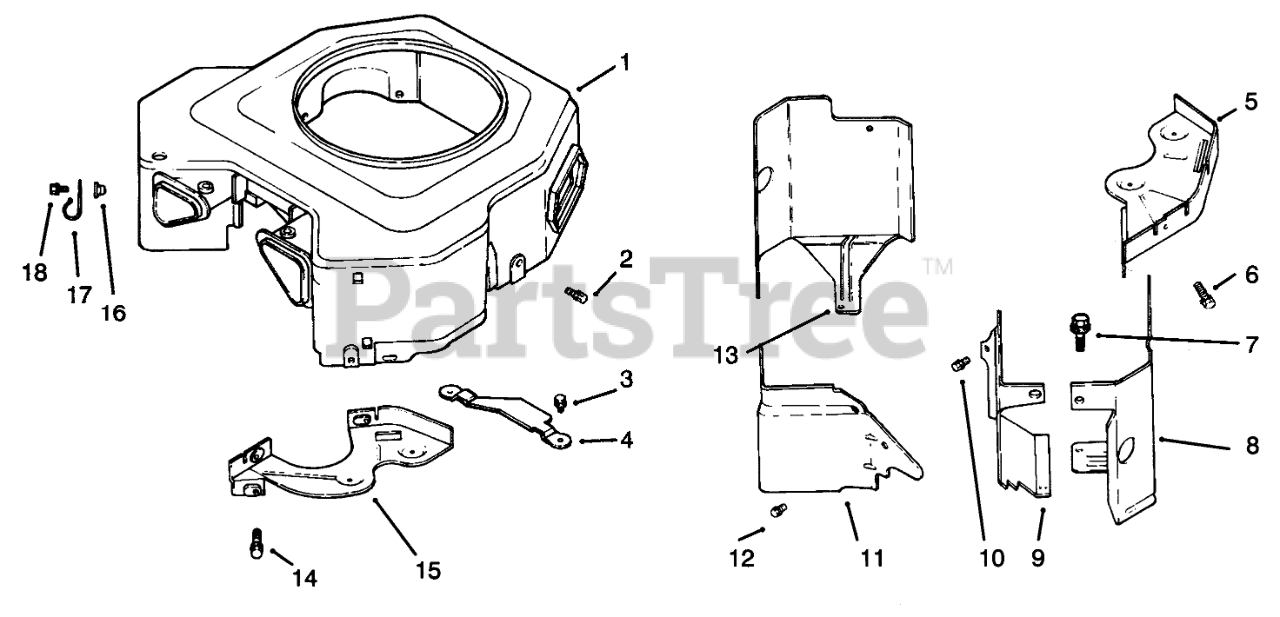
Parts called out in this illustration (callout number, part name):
1	Housing-Blower ASM (Only On: 72103)
2	Screw M5x0.8x16 (Only On: 72103)
3	Screw M6x1.0x16 (Only On: 72103)
4	Guard-Flywheel (Only On: 72103)
5	Plate-Backing #2 Side (Only On: 72103)
6	Screw M5x0.8x20 (Only On: 72103)
7	Screw M5x0.8x14 (Only On: 72103)
8	Baffle-Cylinder #2 Side (Only On: 72103)
9	Baffle-Valley #1 Side (Only On: 72103)
10	Screw M5x0.8x10 (Only On: 72103)
11	Baffle-Valley #2 Side (Only On: 72103)
12	Screw M5x0.8x16 (Only On: 72103)
13	Baffle-Cylinder #1 Side (Only On: 72103)
14	Screw M6x1.0x16 (Only On: 72103)
15	Plate-Backing #1 Side (Only On: 72103)
16	Nut-Plastic (Only On: 72103)
17	Clip-Cable (Only On: 72103)
18	Screw-Cable Clip (Only On: 72103)
